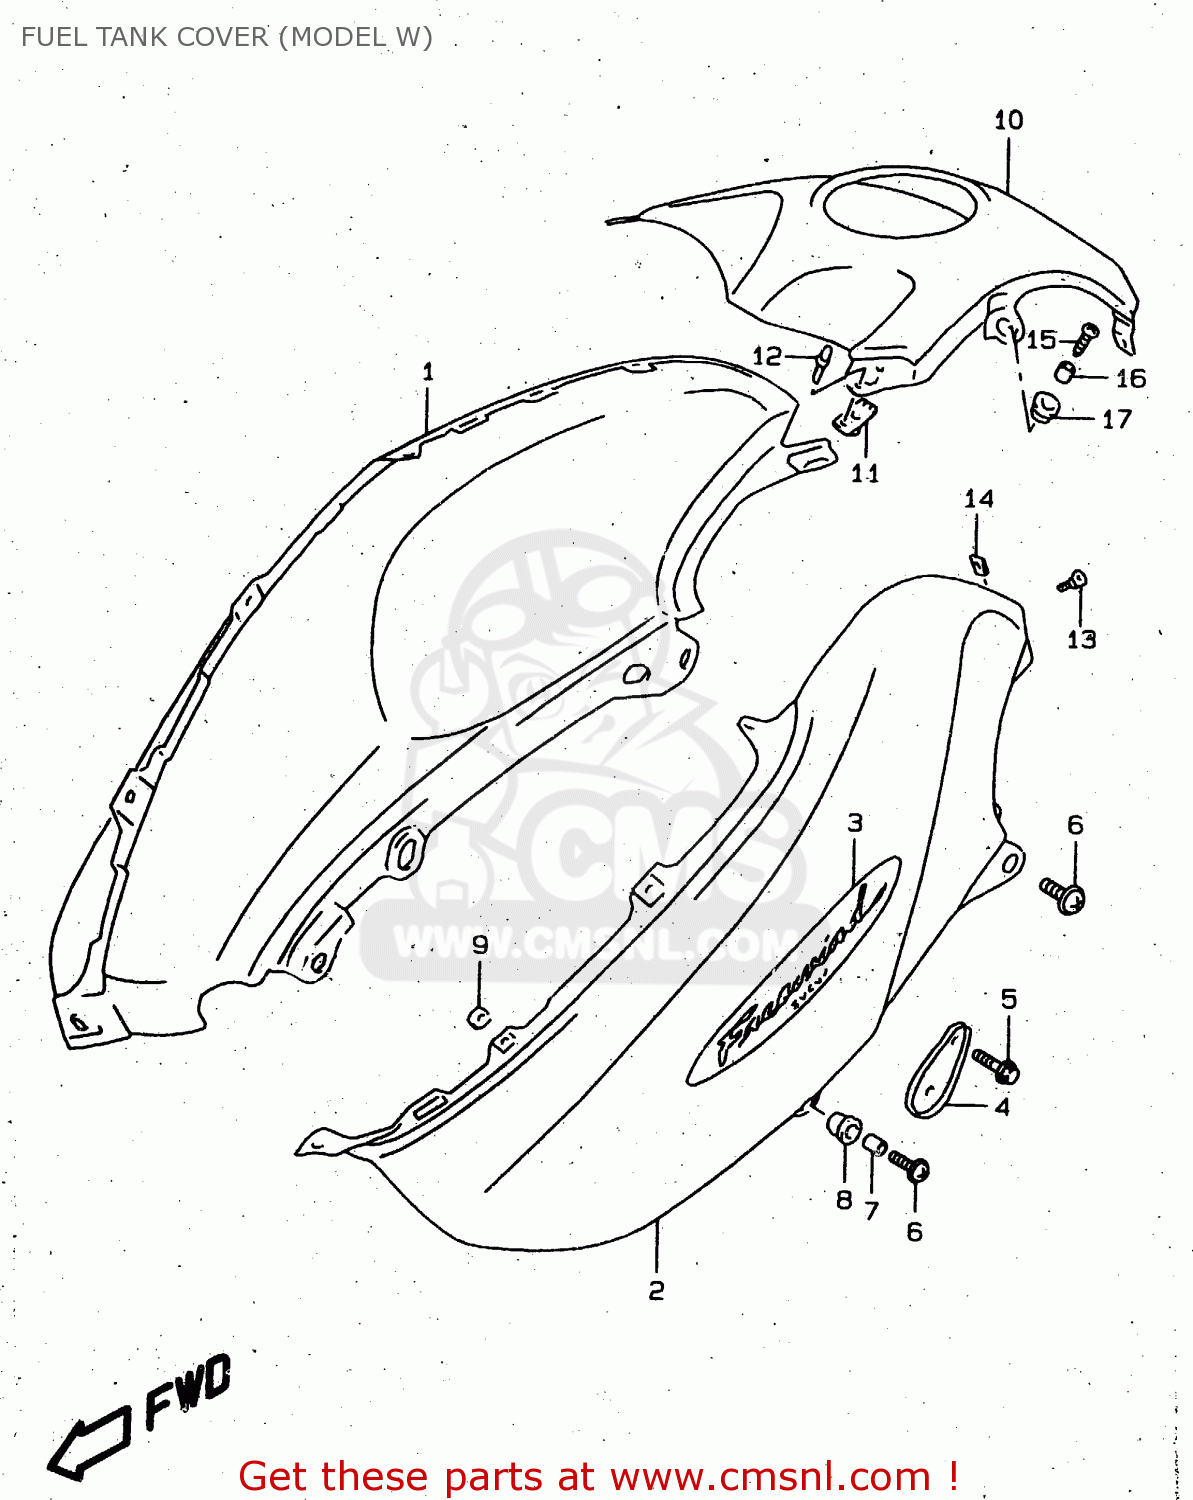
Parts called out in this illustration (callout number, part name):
1	COVER,FUEL TANK,R
2	COVER,FUEL TANK,L
3	EMBLEM,FUEL TANK COVER
4	BRACKET,SIDE COVER,SIDE
5	BOLT
6	SCREW (6X20) WITH WASHER
7	SPACER(6.5X9X10)
8	CUSHION
9	NUT,HEADLAMP HOUSING,UPPER
10	COVER,FUEL TANK UPR
11	PLATE
12	RIVET
13	SCREW(5X16)
14	NUT,HEADLAMP HOUSING,UPPER
15	SCREW (6X20) WITH WASHER
16	SPACER(6.5X9X10)
17	CUSHION
